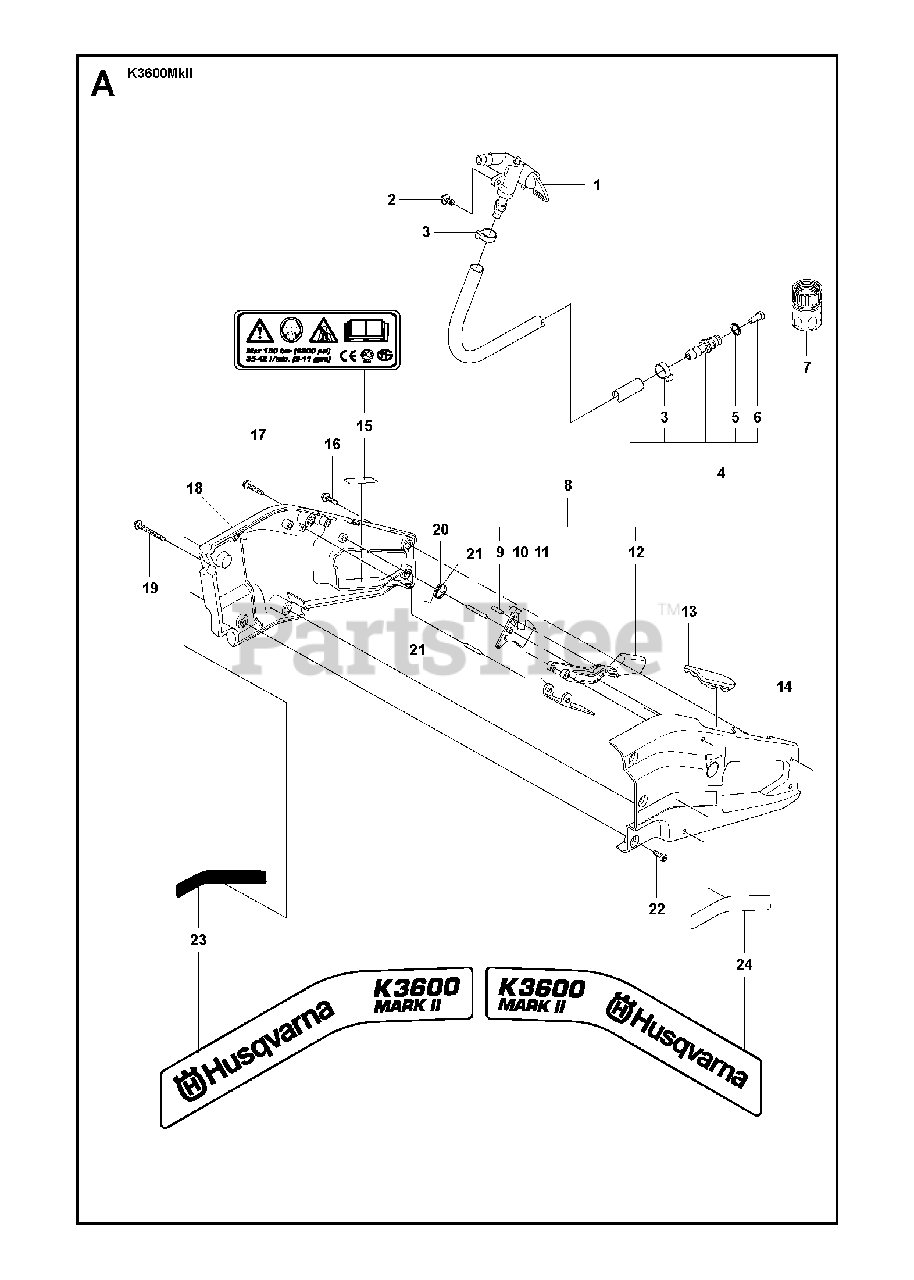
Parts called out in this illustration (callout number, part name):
3	HOSE CLAMP
5	O-RING
6	FILTER
8	THROTTLE TRIGGERIncl. 9 - 12
16	SCREW ITXSCM
17	SCREW ITXSCM
19	SCREW ITXSCM
21	PARALLEL PIN
22	SCREW ITXSCM
25	PARALLEL PIN
